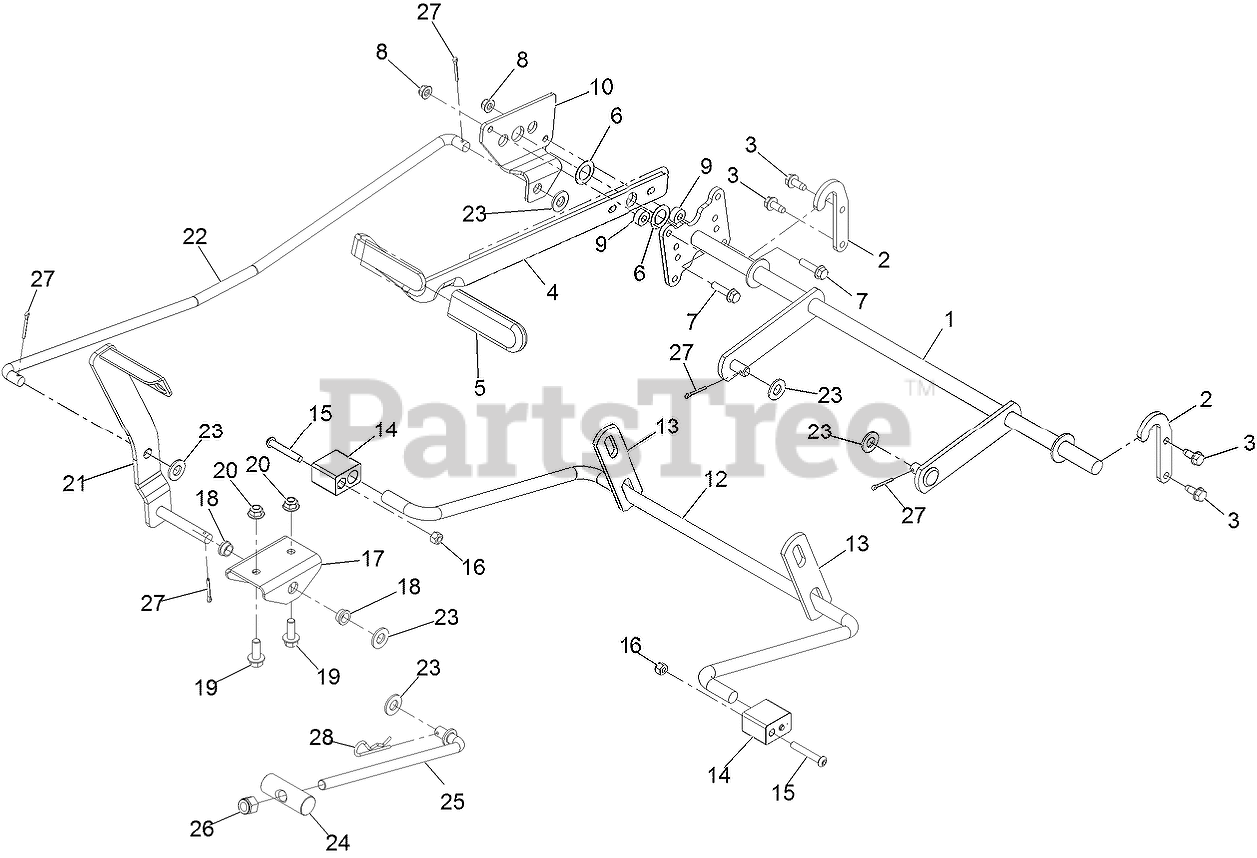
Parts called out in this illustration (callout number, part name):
1	LIFT-DECK, WIDE
2	Bracket-Lift
3	Screw-HWH 5/16-18 X 3/4 Tf
4	HANDLE-DECK LIFT
5	GRIP-LEVER
6	WASHER-THRUST
7	SCREW-HHF
8	NUT-HF, NI
10	PLATE-FOOTLIFT
12	Arm-Lift, Rear (Wide)
13	LINK-LIFT
14	BLOCK-PIVOT
15	SCREW-HSBH
16	NUT-LOCK, NI
17	BRACKET-FOOTLIFT
18	BUSHING-FLANGE
19	SCREW-HHF 3/8-16 X 1
20	NUT-HF, NI
21	PEDAL ASM
22	ROD-FOOTLIFT
23	WASHER-FLAT
24	PIN-PIVOT
25	ROD-MOUNT, DECK
26	NUT-HEX
27	PIN-COTTER
28	PIN-COTTER
